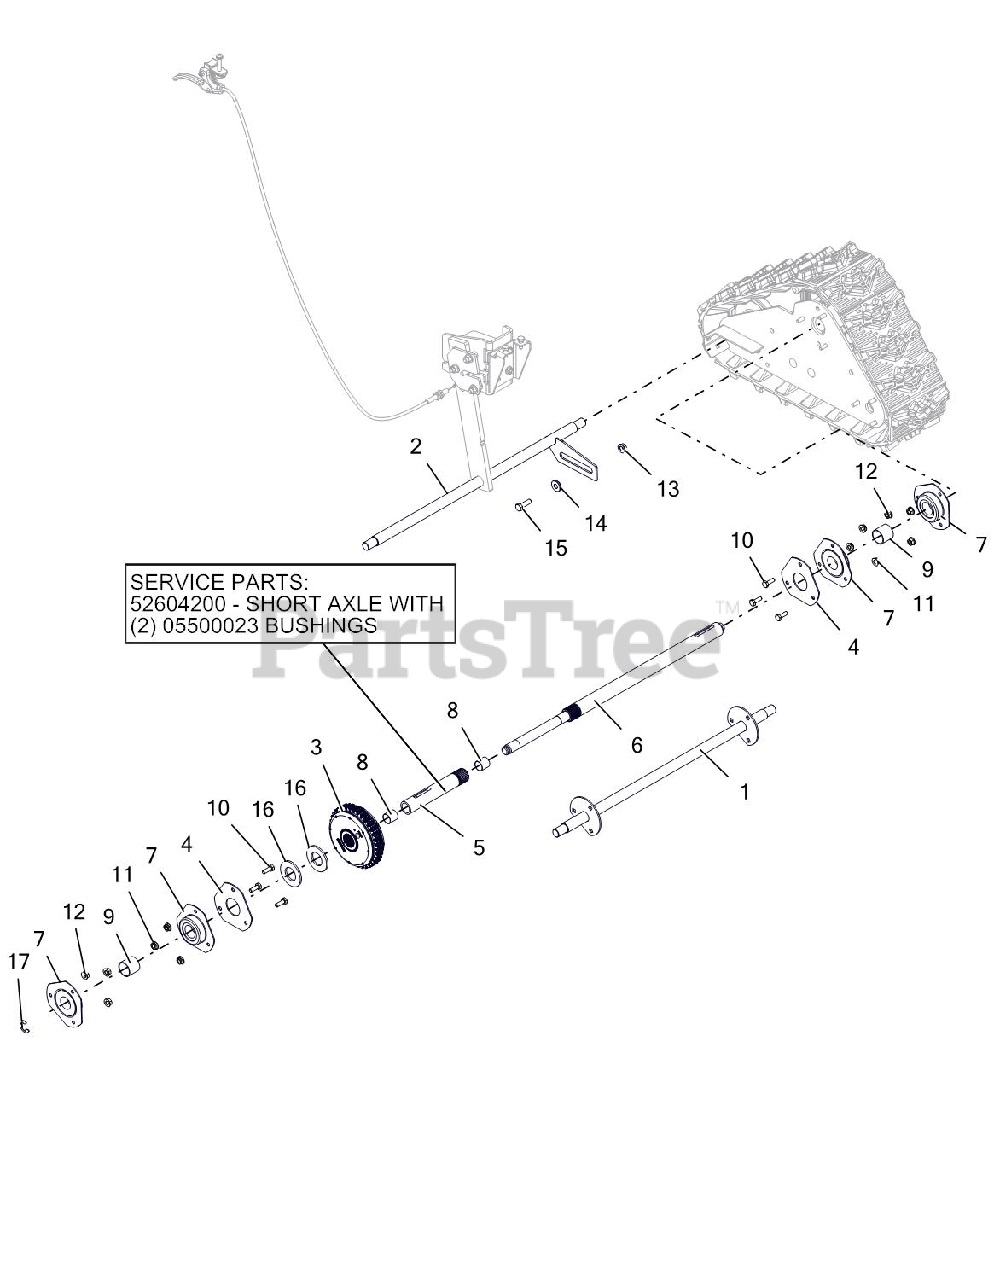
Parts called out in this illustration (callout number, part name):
1	AXLE, FRONT - PRO
2	AXLE, REAR - PRO TRACK
3	DIFFERENTIAL, AUTOMATIC
4	PLATE, BEARING SPACER
5	BSHG-SLV .706X.764X.75 BRZ
5	AXLE, SHORT-TRACK DIFFERENTIAL
5	AXLE, SHORT-TRACK W/BUSHINGS
6	AXLE, LONG-PRO AUTO DIFF
7	BRG-FLG 1.003/1.000 3 BOLT
8	BSHG-SLV .706X.764X.75 BRZ
9	BSHG-SLV, 1.012X1.125X1.00
10	@BLT-HEX .25-20X.75 GR5 YWZC
11	@NUT-LK-CTR-FLG .25-20 YWZC
12	@NUT-LK-TOP-FLG .25-20 YWZC
13	@NUT-LK-TOP-FLG .31-18 YWZC
14	BSHG-FLG .325X.499X.3X.875
15	@BLT-HEX .31-18X1.00 GR5 YWZC
16	WSHR-FL-STL- 1.062X2.0X.134 YZ
17	RG-RTNG-EXT .625X.042
